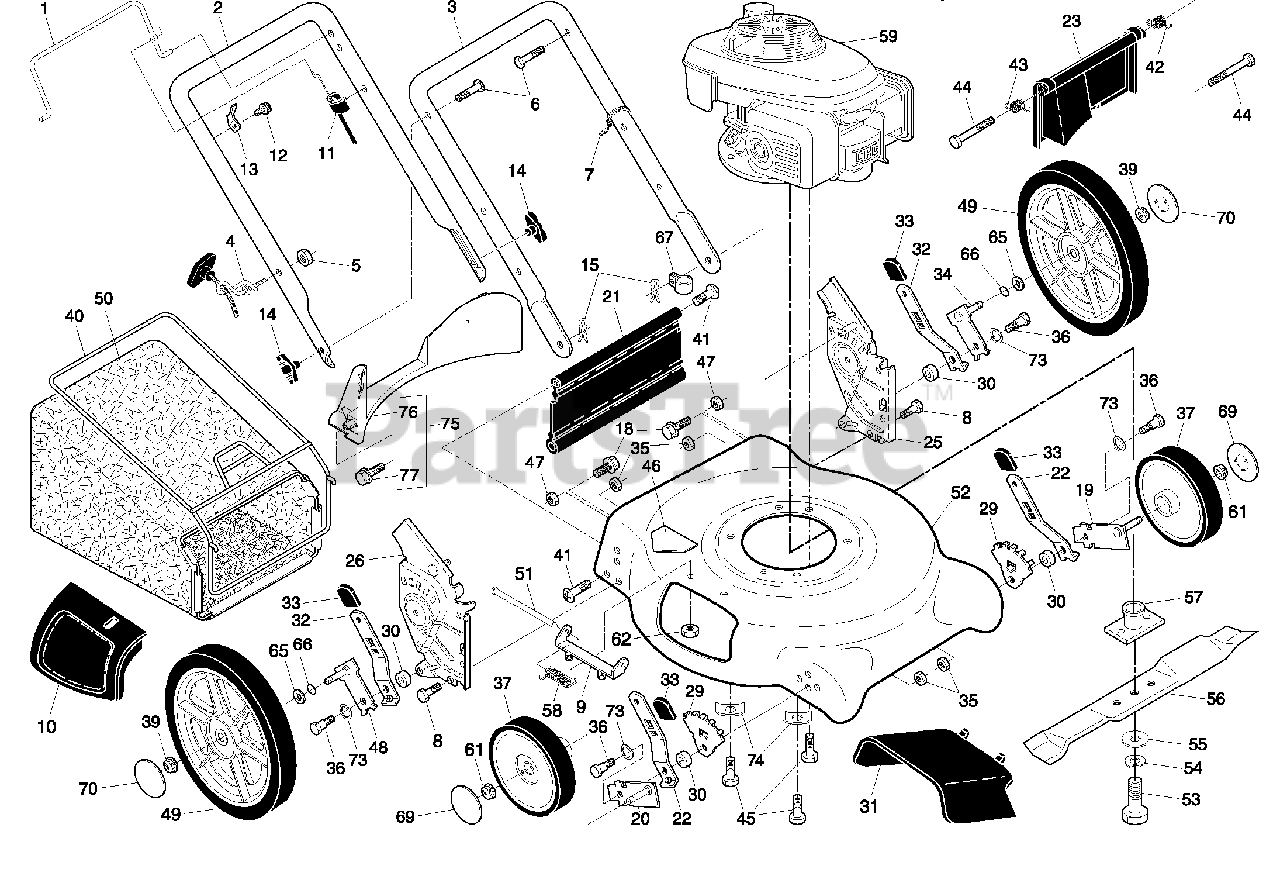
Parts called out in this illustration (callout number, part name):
1	Control Bar
2	Upper Handle
3	Lower Handle
4	Rope Guide
6	Handle Bolt
7	Wire Tie
8	Bolt, Hex Head 5/16-18 x 3/4
9	Hinge Bracket
10	Mulcher Door
11	Engine Zone Control Cable
12	Hex Washer Head Screw #10-24 x 1/2
13	Up-Stop Bracket
14	Handle Knob
15	Hairpin Cotter
18	Screw
19	Axle Arm Assembly, Front, LH
20	Axle Arm Assembly, Front, RH
21	Kit, Rear Skirt
22	Selector Spring, Front
23	Rear Door Assembly
25	Handle Bracket, LH
26	Handle Bracket, RH
29	Wheel Adjusting Bracket
30	Spacer
31	Discharge Deflector
32	Selector Spring, Rear
33	Selector Knob
34	Axle Arm Assembly, Rear, LH
35	Locknut, Hex 5/16-18
36	Shoulder Bolt 5/16-18
37	Wheel & Tire Assembly, Front, 8"
39	Nut, Hex
40	Frame, Grassbag
41	Screw, Hinge
42	Spring, LH
43	Spring, RH
44	Bolt, Rear Door
45	Hex Head Thread Rolling Screw 3/8-16 x 1
46	Danger Decal
47	Nut, Hex
48	Axle Arm Assembly, Rear, RH
49	Wheel & Tire Assembly, Rear 12 x 1-3/4
51	Hinge Rod
52	Kit, Housing
53	Screw, Hex Head, Grade 8 3/8-24 x 1-3/8
54	Helical Lockwasher
55	Hardened Washer
56	21" Blade
57	Blade Adapter
58	Hinge Spring
61	Flanged Locknut
62	Nut, Hex
65	Washer, Flat
66	O-Ring
67	Clip, Cable
69	Hubcap, Front Wheel
70	Hubcap, Rear Wheel
73	Washer, Curved, Cylindrical
74	Washer, Special, Engine
75	Kit, Rear Baffle
76	Baffle, Rear
77	Screw, Rear Baffle
77	Operator's Manual, English
77	Operator's Manual, French
77	Repair Parts Manual
